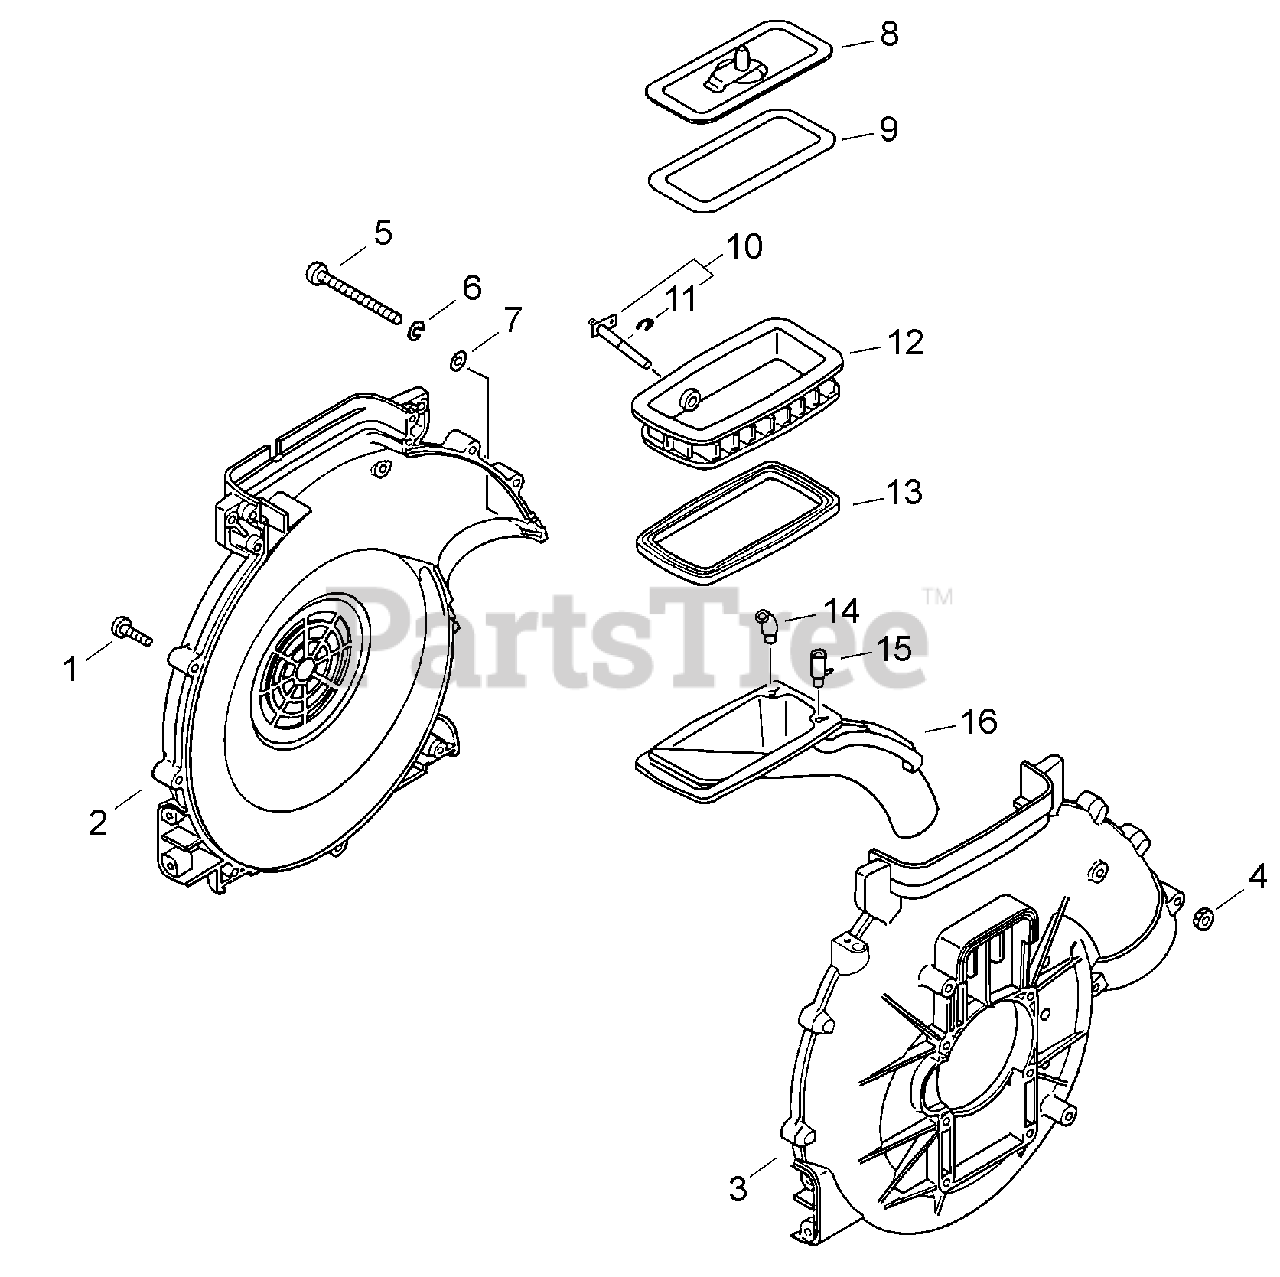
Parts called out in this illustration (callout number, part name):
1	SCREW - 5X25
2	COVER, FAN - INNER
3	COVER, FAN - OUTER
5	BOLT - 5
6	LOCKWASHER - 5
7	WASHER - 5
8	PLATE, DUST OUTLET
9	GASKET
10	SHUTTER SHAFT ASSY
11	RING, RETAINING - 8
12	ADAPTOR, DUST OUTLET
14	GUIDE, AIR
15	GUIDE, AIR
16	PIPE - OUTLET
